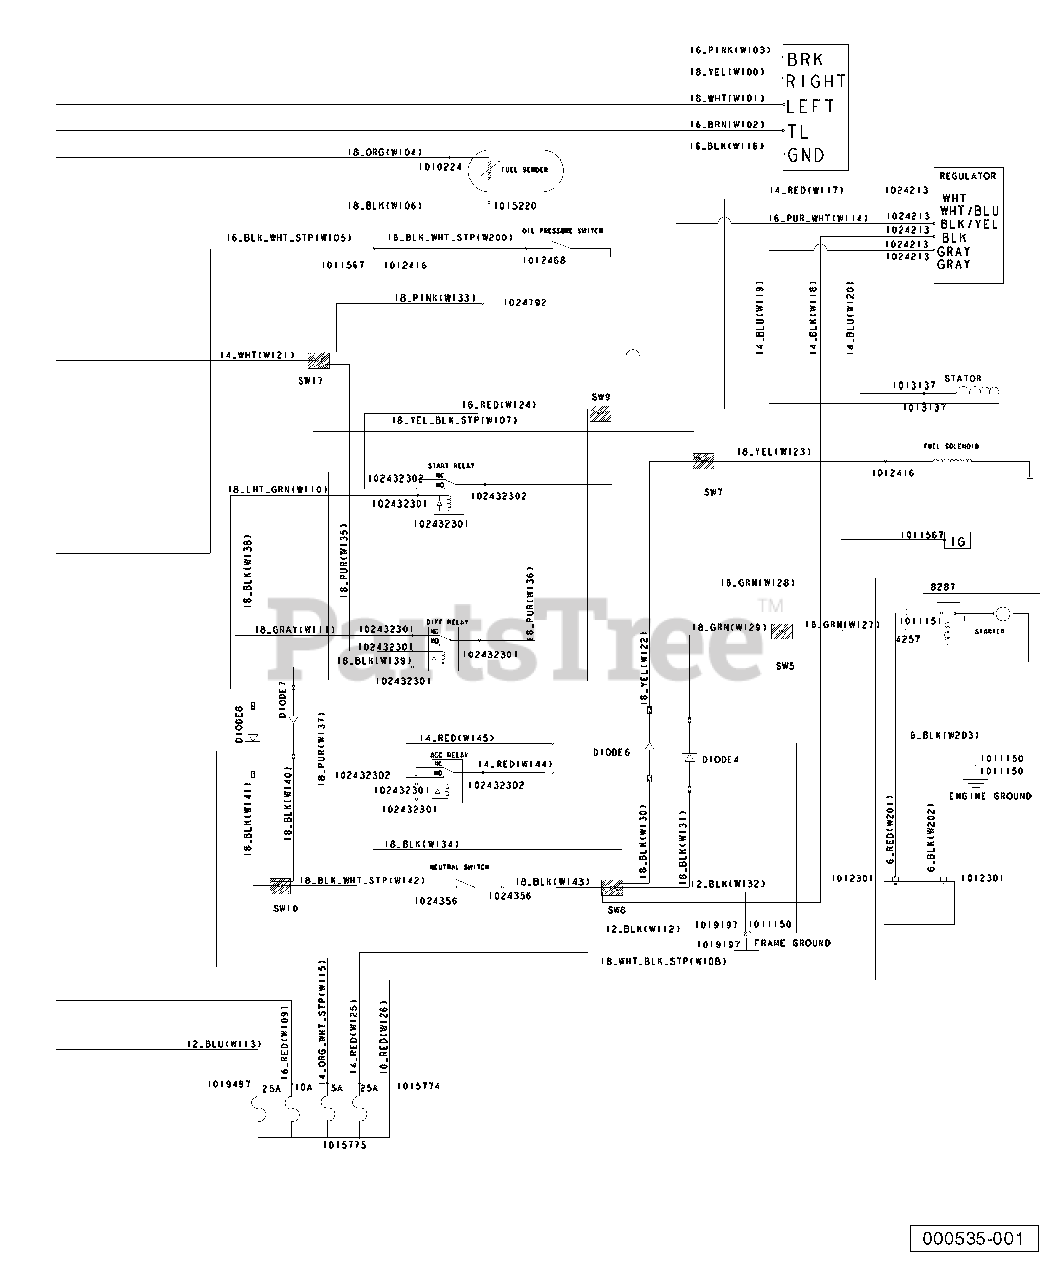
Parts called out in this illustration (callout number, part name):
1	Diode, General Purpose, 6.0a
2	Harness, Restyle Gas, Front
3	Harness, Restyle Gas, Rear
